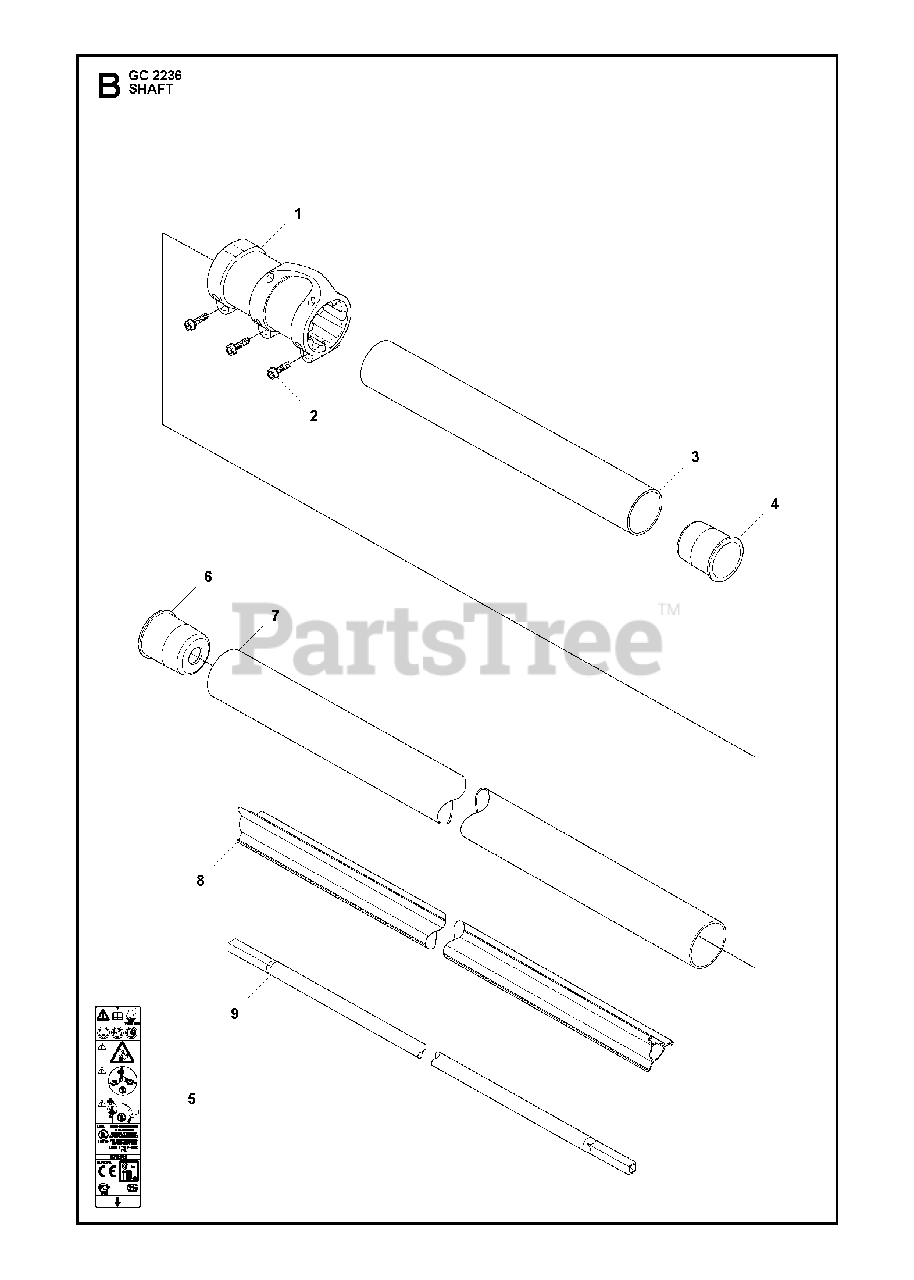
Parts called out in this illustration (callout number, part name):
3	TUBE
4	SPACER SLEEVE
7	TUBE
8	GUIDE
9	SHAFT
